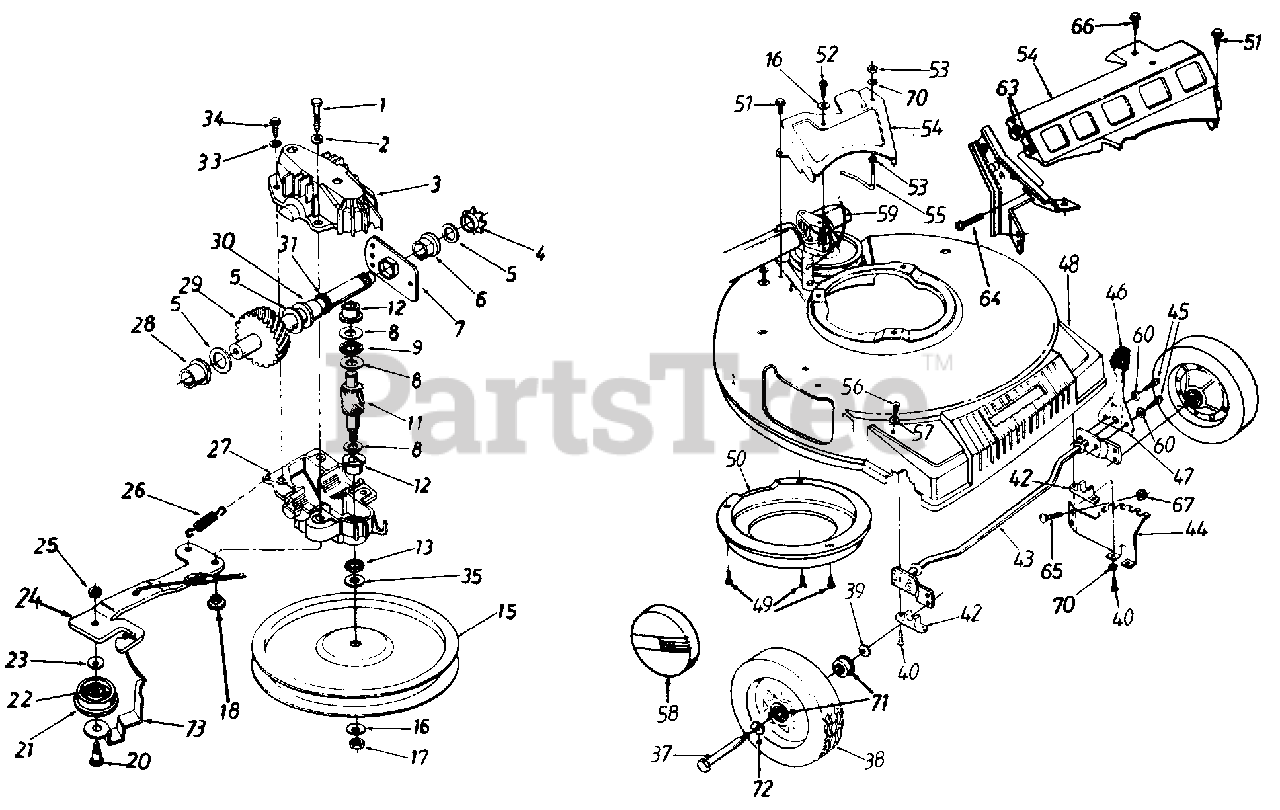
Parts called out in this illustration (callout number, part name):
1	Hex Patch Bolt 1/4-20 x 1.25"
2	L-Wash. 1/4" I.D.
3	Upper Hsg. Half
4	#48 Sprocket 7 T x 1/2 Pitch
5	Fl-Wash. 5/8" I.D. x .030
6	Hex Flange Brg. .631" I.D.
8	Thrust Wash. .382" I.D. x .70" O.D.
9	Thrust Bearing .375" I.D. x 812" O.D.
11	11 Tooth Pinion Shaft
12	Flange Bearing
13	Oil Seal
15	Fl-Pulley 5.06" O.D.
16	Bell-Wash. .265" I.D. x .75"
17	Hex L-Nut 1/4-28 L.H. Thd.
18	Shld. Spacer .375" Dia. x .170
20	Shld. Bolt .375" Dia. x .40"
21	Fl-Idler Plastic 1.50" Dia.
22	Needle Brg. .375" x .31
24	Idler Brk't. Ass'y.
25	Hex Patch L-Nut 1/4-28 Thd.
26	Extension Spring 1.12" Lg.
27	Lower Hsg. Half
28	Flange Bearing .566 Dia.
29	Shaft Ass'y.
30	Flange Bearing .629 Dia.
31	Oil Seal .625 Dia.
33	L-Wash. #10 I.D.
34	Hex B-Tap Scr. #10 x .62"
35	Hex Washer .26" x .88"
37	Front Axle Bolt
38	Wheel Ass'y. Comp. (Gray Rim)
39	Bell-Wash. .380" I.D. x .88
40	Hex Wash. Hd. Scr. 1/4 x 1" Lg.
42	Block Bushing
45	Hex TT-Tap Scr. 1/4-20 x .38"
46	Knob
47	Spring Lever
48	Plastic Front End (Black)
49	Hex B-Tap Scr. 1/4" x .38"
52	Hex Wash. Hd. B-Tap Scr. 1/4 x .62" (Spec.)
53	Hex Nut 1/4-20 Thd.
54	Transmission Belt Cover
56	Torx Truss Hd. Scr. 5/16 x .75"
57	Bell-Wash. .345" I.D. x .88"
58	Hub Cap
59	S.P. Cable
60	External L-Wash. 1/4" I.D.
63	Speed Nut #10-24 Thd.
64	Hex Tap Scr. #10-16 x .5" Lg.
65	Carr. Bolt 1/4-20 x .5" Lg.
66	Hex B-Tap Scr .5/16-18 x .5" Lg.
67	Hex Flange L-Nut 1/4-20 Thd.
70	L-Wash. 1/4" I.D.
71	Wheel Bearing
72	Wave Washer
